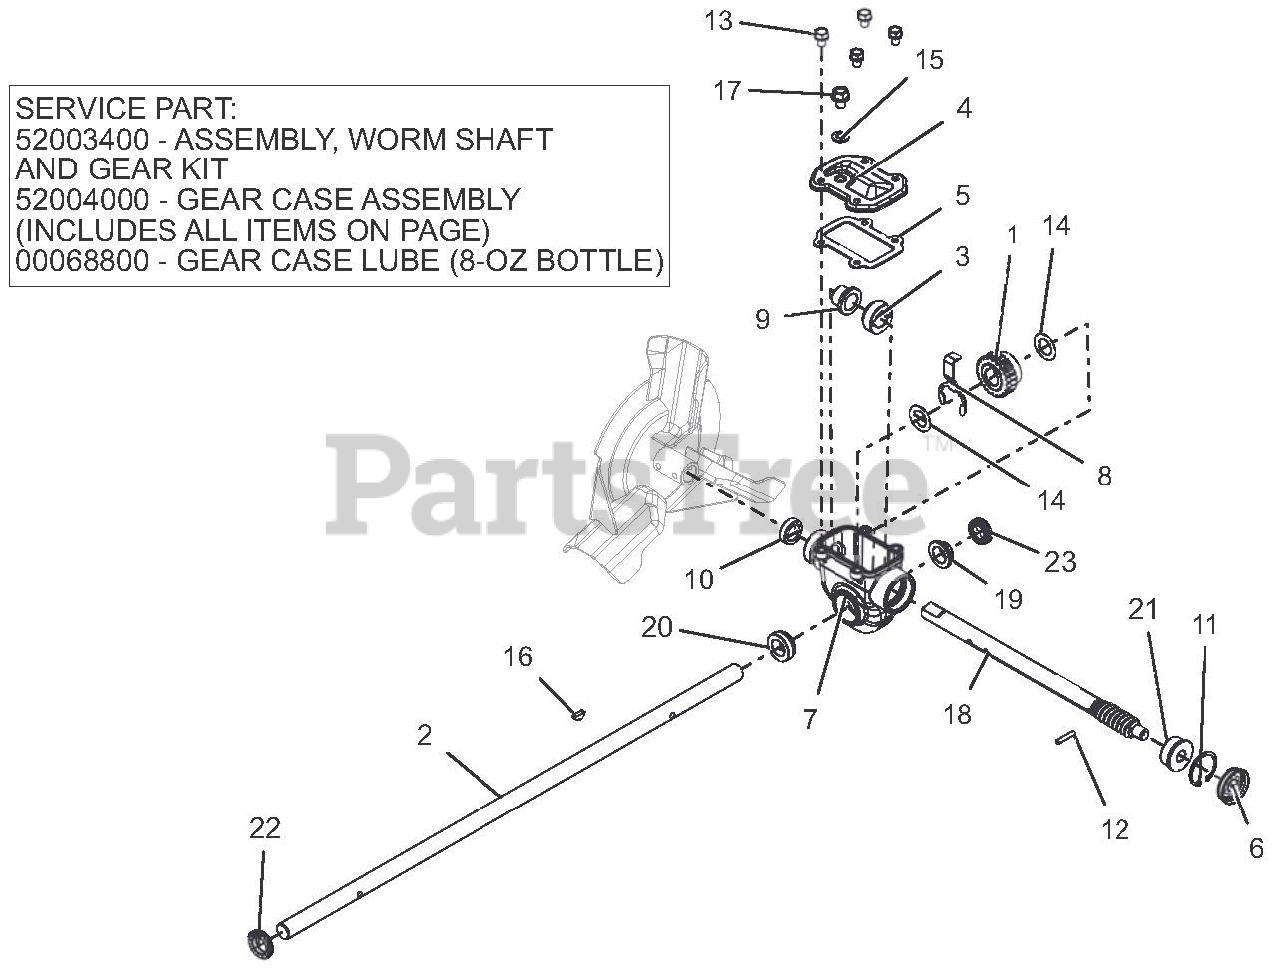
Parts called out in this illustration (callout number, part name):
1	WORM GEAR
2	SHAFT, RAKE-28" (.750 DIA)
3	THRUST COLLAR, .75" ID SLIPFIT
4	COVER, TOP - COMPACT
5	GASKET, TOP - COMPACT GEARCASE
6	COVER, GEAR CASE 1.50"
7	GEARCASE, COMPACT ALUMINUM
8	BUSHING RETAINER, COMPACT
9	BSHG-FLG .755X.878X.75X1.25
10	SEAL-OIL .748X1.125X.312 TB2-H
11	RG-RTNG-INT 1.500X.050
12	PIN-STR .188X1.00 6150
13	BOLT, SEMS .31-18X.50 GR5 YWZC
14	WSHR-FL-STL .760X1.225X.032 YZ
15	WSHR-BND-SEAL .38X.75X.11 GALV
16	KEY-WDRF .19X.63 HRD #61
17	@SCR-ROLOK .38-16X.50 HWH YWZC
18	SHAFT, WORM - COMPACT
19	BSHG-FLG .755X.878X.424X1.25
20	BSHG-FLG COMPACT, RIGHT
21	BSHG-FLG .503X1.303X.62X1.465
22	SEAL-OIL .748X1.300X.250 TBC29
23	SEAL-OIL .748X1.125X.312 TBC29
24	GEAR CASE, 28" ALUM SM TOP-LD
25	ARIENS L3 LUBE, 8 OZ BOTTLE
